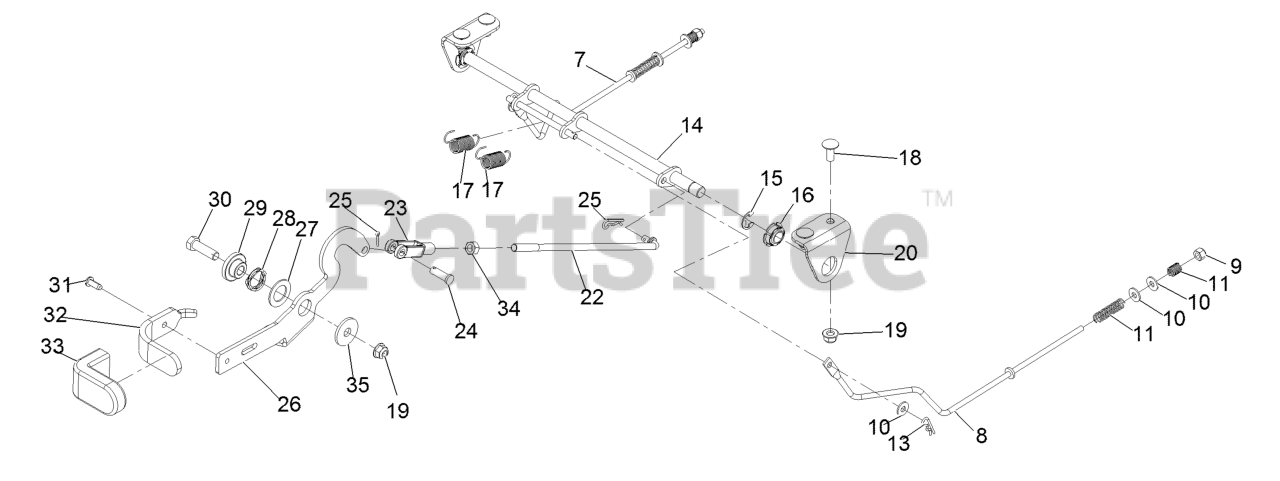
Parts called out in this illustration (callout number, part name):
7	Rod-Brake, RH
8	Rod-Brake, LH
9	Nut-Nyloc 1/4-20
11	Spring-Compression
13	Pin-Cotter
14	Pivot-Brake
15	Ring-Retaining
16	Bearing-Spherical
17	Spring-Extension
18	Bolt-Carriage 5/16-18 X 3/4 Short Neck
19	Nut-Nyloc 5/16-18 Flg
20	Angle-Mount Pivot
22	Rod-Link Handle
23	Yoke-Adjustable
24	Pin-Clevis 5/16 X 1 49/64
25	Pin-Cotter 3/32 X 1/2
26	Lever-Brake
27	Washer-Thrust
28	Washer-Wave
29	Pivot-Flange
30	Screw-HH 3/8-16 X 1 1/4
31	Screw-Button Head 1/4-20 X .62 Tf
32	Handle-Brake
33	Grip-Lever
34	Nut-Hex 5/16-24
35	Washer
